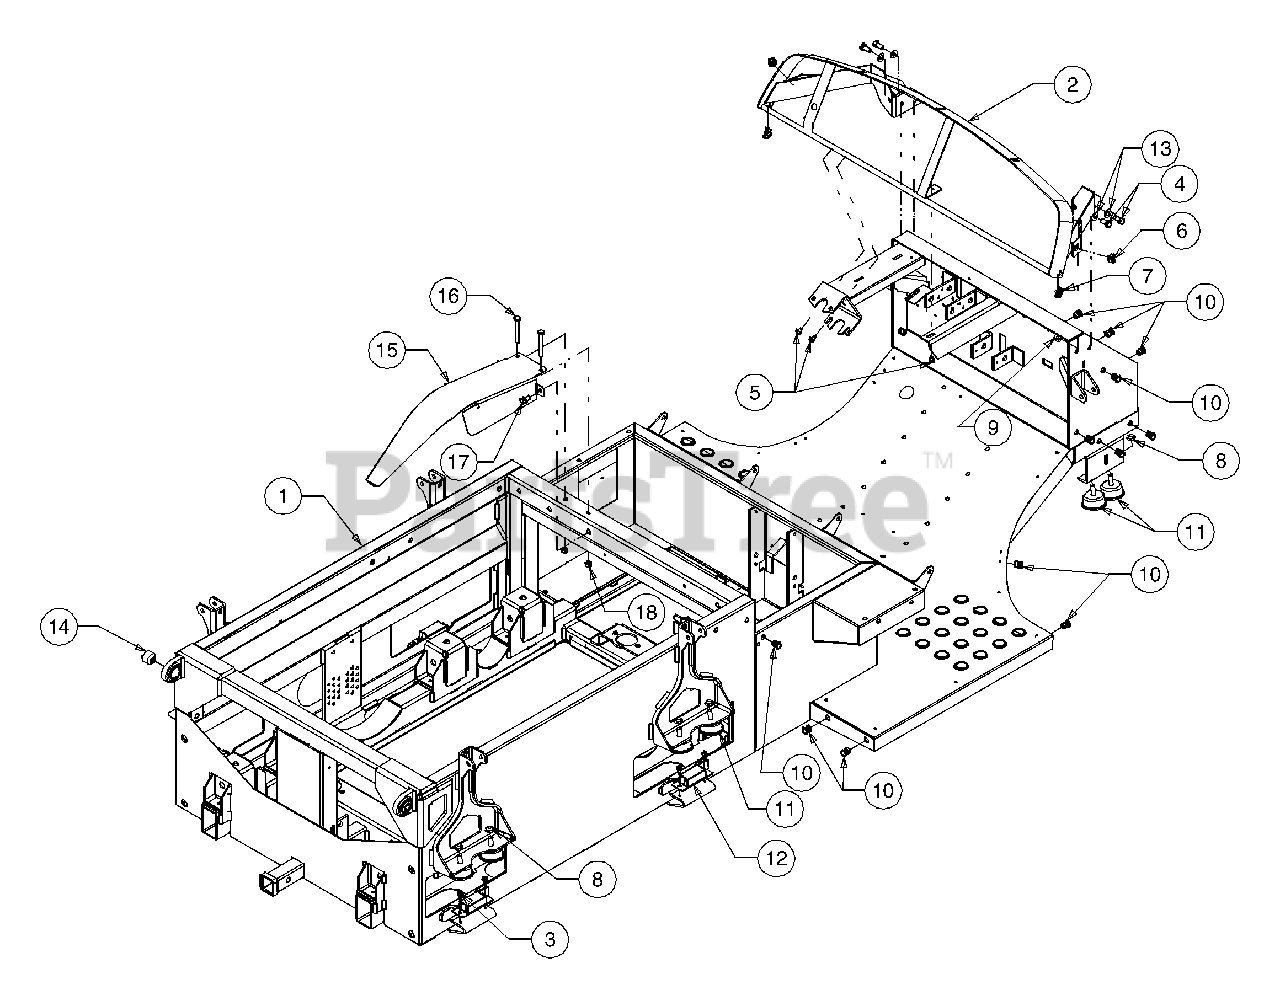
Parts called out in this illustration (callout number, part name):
1	Frame Assembly, Complete
2	Frame Assembly, Upper Dash
3	Screw, Self-tapping, 1/4-20 x 0.500
4	Screw, Hex, 3/8-16 x .75
5	Screw, Self-tapping, 1/4-20 x .375
6	Nut, Retainer, 5/16-18
7	U-Nut, 1/4-20
8	Nut, Nylon Lock, M10-1.25
9	Nut, Flange Lock, 3/8-16
10	Nut, Insert, 5/16-18
11	Bumper, Compression Suspension
12	Bumper, Compression Extension
13	Washer, Flat, .406 x 812 x .51
14	Rubber Bushing, Bed Pivot
15	Guard, Belt
16	Hex Screw, 5/16-18 x 2.5, Gr5
17	Hex Screw, Flange, 5/16-18 x .625, Gr5
18	Nut, Hex Lock, 5/16-18
